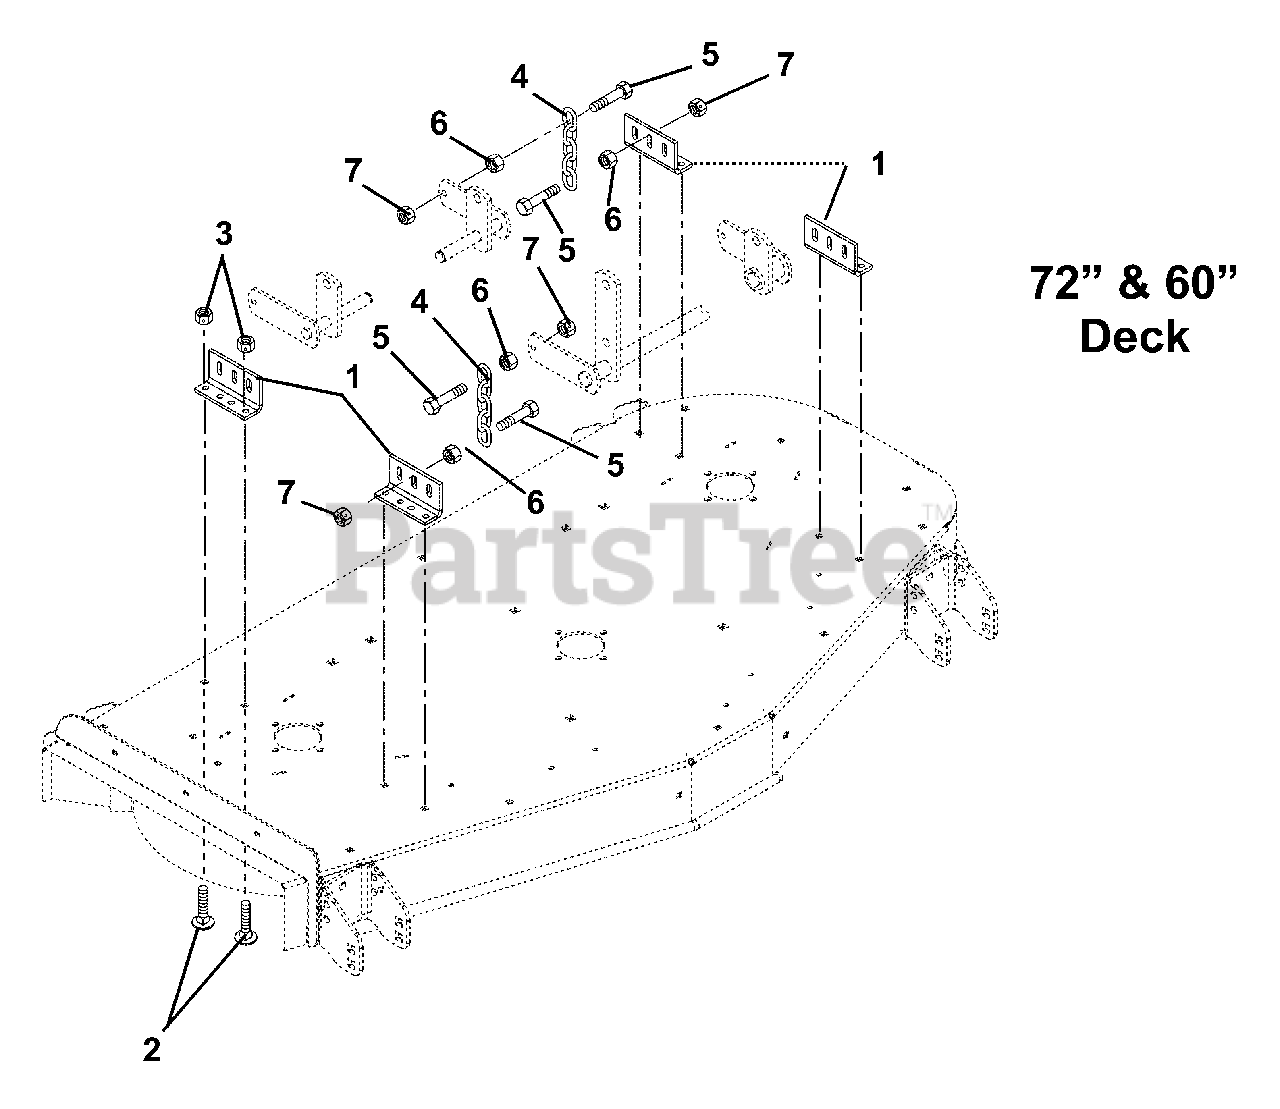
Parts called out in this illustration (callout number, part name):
1	Bracket, Mower Mounting
2	Bolt-Round Head Square Neck .38-16 x 1.00 Grade 2
3	Nut-Locking-Top-Flange .38-16
4	Chain, Link
5	Bolt-Hex M12-1.75 Grade 5
6	Nut, Spin Lock Flange M12-1.75
7	Nut-Locking-Top-Flange M12-1.75
